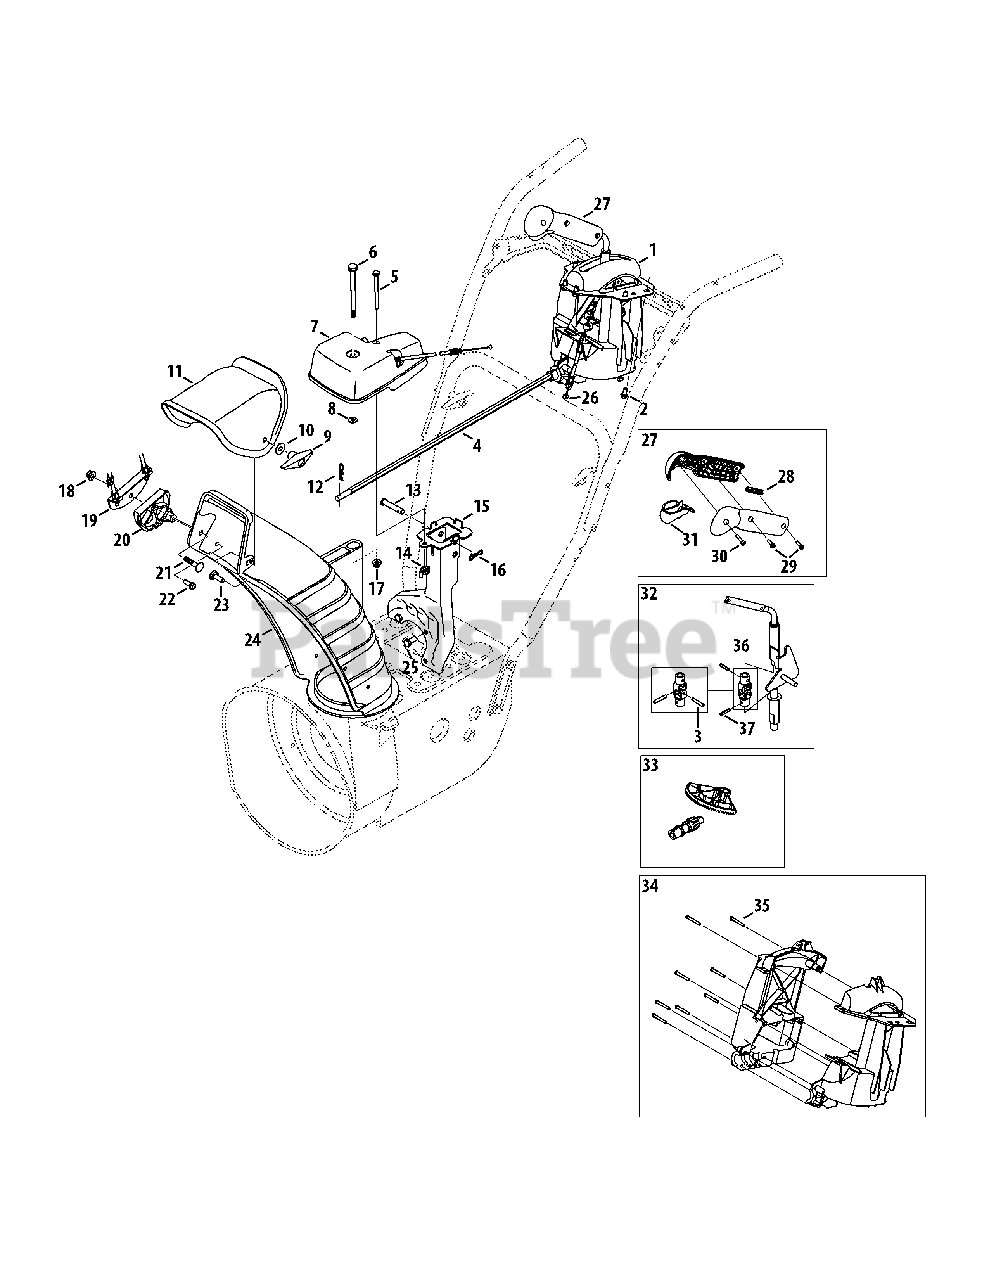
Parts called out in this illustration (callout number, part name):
1	4-Way Chute Control™ Assembly
2	Hi-Lo Screw, 1/4-15 x 0.5
3	Roll Pin
4	Chute Rod
5	Hex Screw, 1/4-20 x 3.00
6	Flange Shoulder Screw
7	4-Way Chute Gearbox Assembly
8	Flat Washer, .25 x .630 x .0515
9	Wing Knob
10	Flat Washer, .349 x .879 x .063
11	Upper Chute
12	Cotter Pin
13	Clevis Pin
14	Wing Nut, 1/4-20
15	Chute Support Bracket
16	Bow Tie Cotter Pin
17	Flange Lock Nut, 1/4-20
18	Flange Lock Nut, 5/16-18
19	Cable Bracket
20	Chute Tilt Cable Guide
21	Carriage Bolt, 5/16-18 x 1.50
22	Hi-Lo Screw, 1/4-15 x .75
23	Carriage Bolt, 5/16-18 x 1.0
24	Lower Chute
25	Hex Screw, 5/16-24 x .750
26	4-Way Cable
27	Handle Assembly
28	Handle Plunger
29	Screw, Mach., #8-32 x .750
30	Screw, #8 x 1.00
31	Handle Lever
32	Shift Assembly
33	Gear Set Assembly
34	Handle Housing Assembly
35	Screw, #8-18 x 1.250
36	Joint Block Assembly
